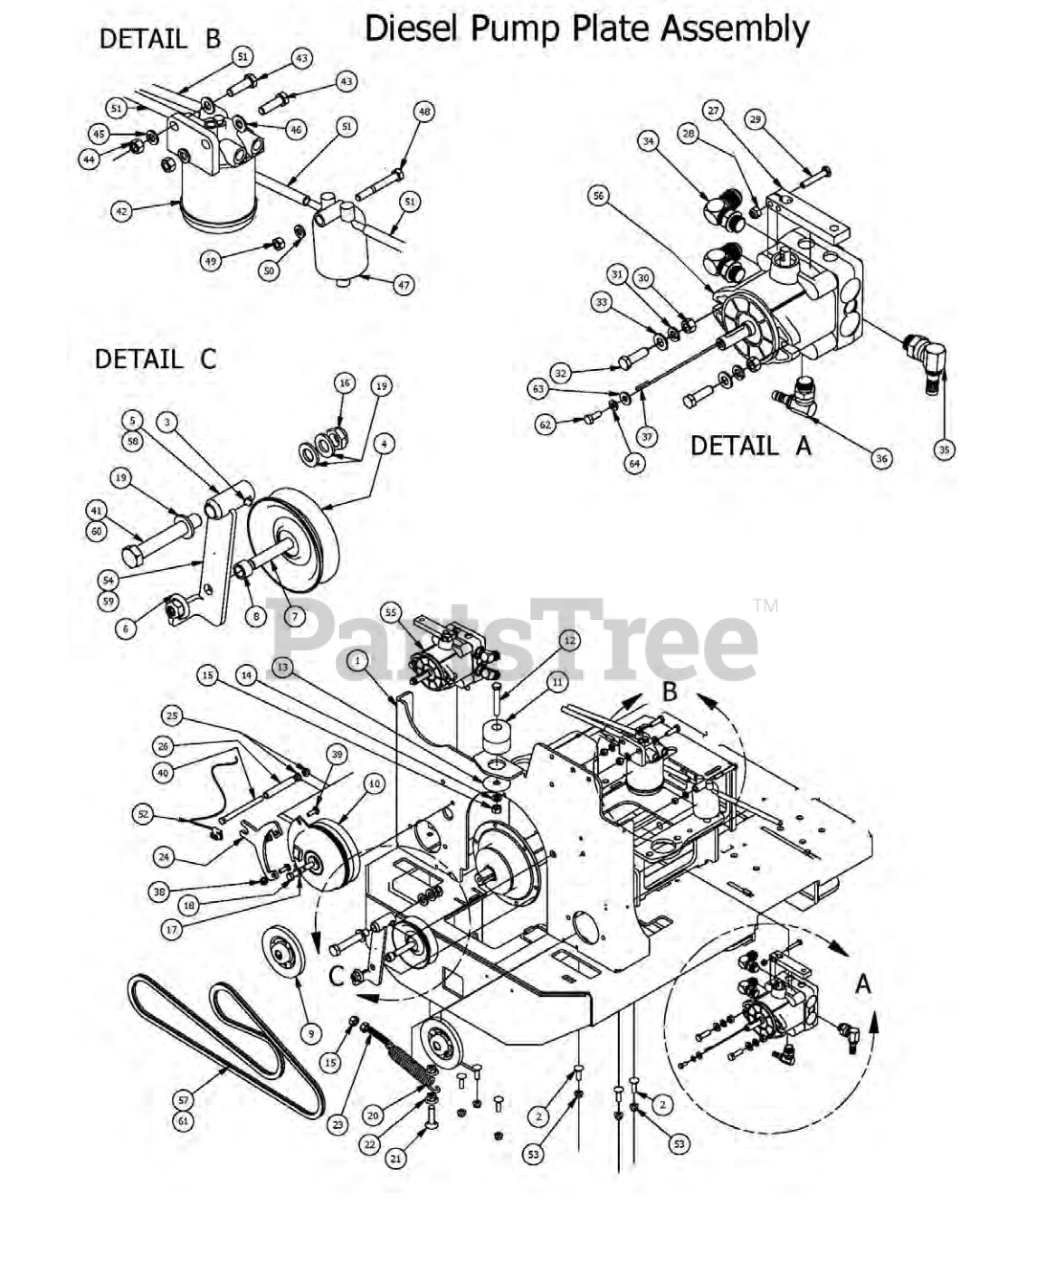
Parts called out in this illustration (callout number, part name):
1	Pump Plate Diesel
2	3/8" 1 1/4" Carriage Bolt
3	1/4" Drive in Grease Fitting
4	4 3/4" Idler Pulley
5	Pump Idler Bracket only for 61" Deck
6	1/2-13 Nylon Flange Nut-Orange
7	1/2" x 3" Hex Bolt
8	1/2 x 1/2 Spacer
9	5 Pump Pulley
10	Clutch Assembly for Diesel
11	Armor Plated Mount-Rear Mount
12	1/2 x 3" Hex Bolt
13	Snubbing Washer
14	1/2 Lock Washer
15	1/2" Hex Nut
16	5/8 Nylock (1/2 Jam)
17	7/16" Lock Washer
18	7/16" 2 3/4" Fine Thread Bolt
19	.630 IDx 1.122 OD.142 THK Plastic Washer
20	Deck Idler Spring
21	1/2 x 2" Carriage Bolt
22	1/2-13 Nylon Flange Nut-Orange
23	1/2-13 x 2-1/2 All Thd Stud
24	Diesel PTO Engager Holder
25	3/8 Flange Nut
26	3/8 hase 4" long
28	1/4" Nylock Nut
29	1/4" 1 1/2" Bolt
30	3/8 Hex Nut
31	3/8 Lock Washer
32	3/8" x 1 1/2" Hex Bolt
33	3/8 Flat Washer
34	90 Degree Adaptor 6801-L-8-8 Fitting
35	90 Degree Fitting 1/2" x 3/4" 4601-8-8
36	90 Degree Fitting 3/8" X 9/16"-4601-6-6
37	Smm x 1,25 Key
38	5/16" Flange Nut
39	5/16" x 1" Carriage Balt
40	3/8-16 x 5 Hex Bolt - Grade 5
41	5/8" x 4" Hex Bolt 61" Deck only
42	Fuel Filter
43	3/8" 1 1/4" Hex Bolt
44	3/8" Hex Nut
45	3/8" Lock Washer
46	3/8 Flat Washer
47	Caterpillar Fuel Bowl Kit
48	5/16" x 2 1/2" Bolt
50	5/16" Lock Washer
51	5/16" fuel line hose
52	Clutch Pigtail
53	3/8 Nylock Flange Nut
54	Pump Idler Assembly Components 3,4,5,6,7,8, only for 61" Deck
55	Left Pump 16cc-AOS Diesel 35Hp Diesel
56	Right Pump 16cc-AOS Diesel 35Hp Diesel
57	Pump Belt for 72" Deck
58	Diesel Pump Idler only on 72" Deck
59	Diesel Purp Idler Assembly Components 3,4,5,6,7,8,9,10 only for 72" Deck
60	5/8 x 5 1/2 Bolt only for 72" Deck
61	Pump Belt for 61" Deck
62	M6-1.0 X16MM Hex Bolt
63	1/4" Flat Washer
64	1/4 Lock Washer
